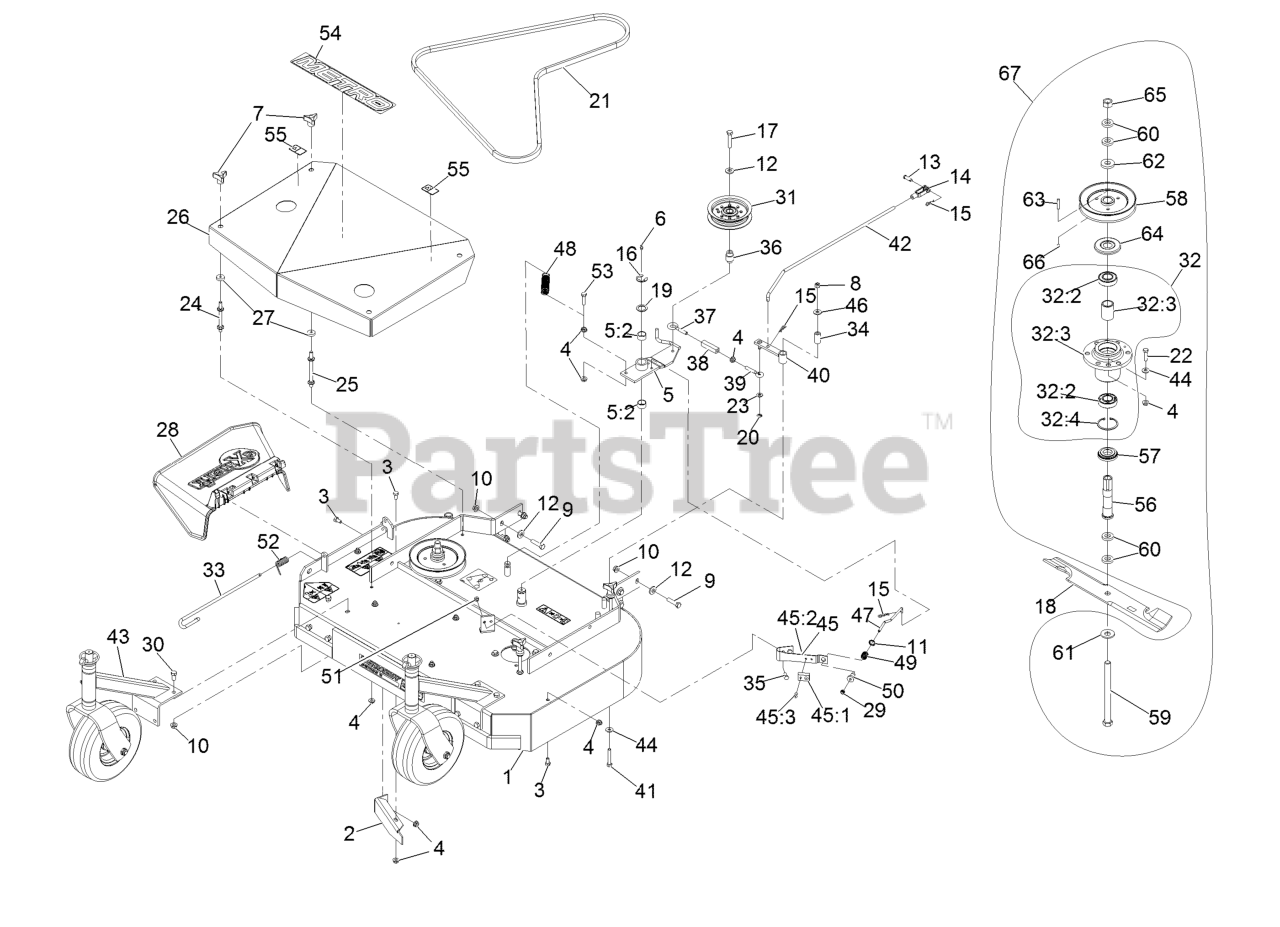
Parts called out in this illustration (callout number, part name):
1	Deck W/Decals And Dogleg
2	Baffle-Dogleg
3	Screw-HH 5/16-18 X 5/8
4	Nut-Whizlock 5/16-18
5	Idler Arm ASM
5:2	Sleeve-Bearing
6	Zerk-1/4-28 Str
7	Knob-3 Prong
8	Nut-Nyloc 5/16-18
9	Screw-HH 3/8-16 X 1 1/2
10	Nut-Whizlock 3/8-16
11	Ring-Push On
12	Washer-Spring Disc 3/8
13	Pin-Clevis 5/16 X 1 49/64
14	Yoke-Adjustable
15	Hairpin-Cotter
17	Screw-HH
18	Blade, 18.00 Mulching
18	Blade, 18.00 Notched
18	Blade-Extreme 2, 18.00"
18	Blade, 18.00 Low Lift
18	Blade, Solid 18.00
19	Washer-Spindle
21	Drive Belt (To Blades)
22	Screw-HH 5/16-18 X 1 1/4
23	Washer-5/16 SAE
24	Stud-Shield, Belt (Short)
25	Stud-Shield, Belt (Long)
26	ASM,Shield W/Decals 36 Metro
27	Washer-Belt Shield
28	Deflector-Discharge
29	Nut-Nyloc 1/4-20 Thin
30	Screw-HH 3/8-16 X 3/4
31	Pulley-Idler
32	Asm, Cutter Housing W/Bearings
32	Cutter Housing ASM
32:2	Bearing-Jackshaft
32:3	Spacer-Bearing
32:4	Ring-Retaining
33	Pin-Chute
34	Tube-Pivot
35	Screw-HH 1/4-20 X 3/4
36	Bushing-Engagement
37	Eyebolt-Thread, LH
38	Body-Turnbuckle
39	Eyebolt-Thread, RH
40	Arm-Assist, 32/36
41	Screw-HH 5/16-18 X 2
42	Arm-Assist, Linkage
43	ASM-Caster Mnt W/Weight
44	Washer-Spring Disc 5/16
45	Pad And Spring ASM
45:1	Pad-Brake
45:2	Spring
45:3	Rivet 3/16 X 1/2
46	Washer-5/16 Std
47	Rod-Brake
48	Spring-Extension
49	Spring-Compression
50	Spacer-Flanged
51	Nut-Nyloc 1/4-20
52	Spring, Torsion
53	Screw,HH Special 5/16-18 X 1.25
54	Decal-Metro
55	Decal-Warning
56	Tube-Spindle, Short
57	Spacer-Guard Bottom
59	Screw-Cap, HH
60	Spacer-Blade Drive
61	Washer-Spring Disc 5/8
63	Key-Machine 1/4 X 3/16 X 1 1/4
64	Guard-Bearing Top
65	Nut-Hex 5/8-18
66	Setscrew-5/16-18 X 3/8
67	Asm, Cutter Housing Complete
